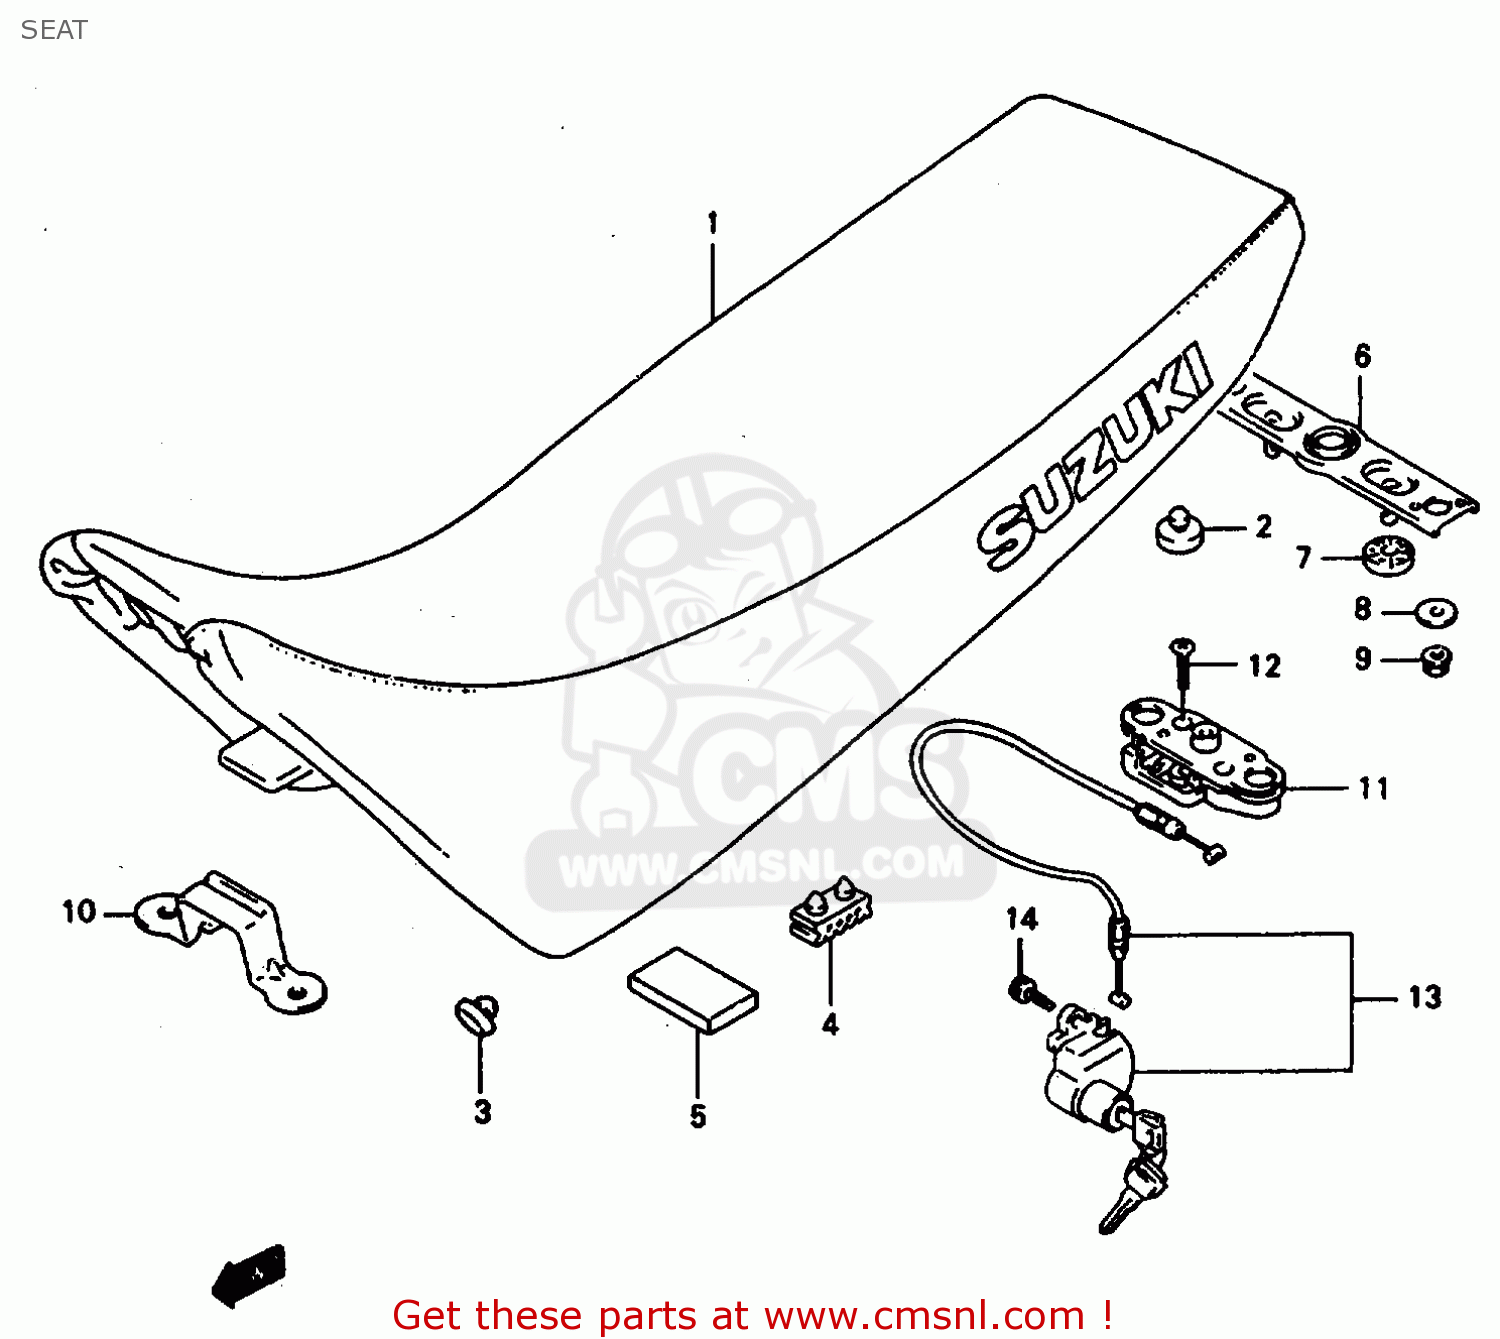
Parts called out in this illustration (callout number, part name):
1	SEAT SET
2	CUSHION
3	CUSHION
4	CUSHION,SEAT(40X20X15)
5	CUSHION,BATTERY
6	STRIKER,SEAT LOCK
7	CUSHION,SEAT LOCK(10X22X6)
8	WASHER
9	NUT
10	BRACKET,SEAT FR FOOK
11	BRACKET,SEAT SUPPORT,RIGHT
12	SCREW
13	LOCK SET, SEAT
14	BOLT(6X12)
